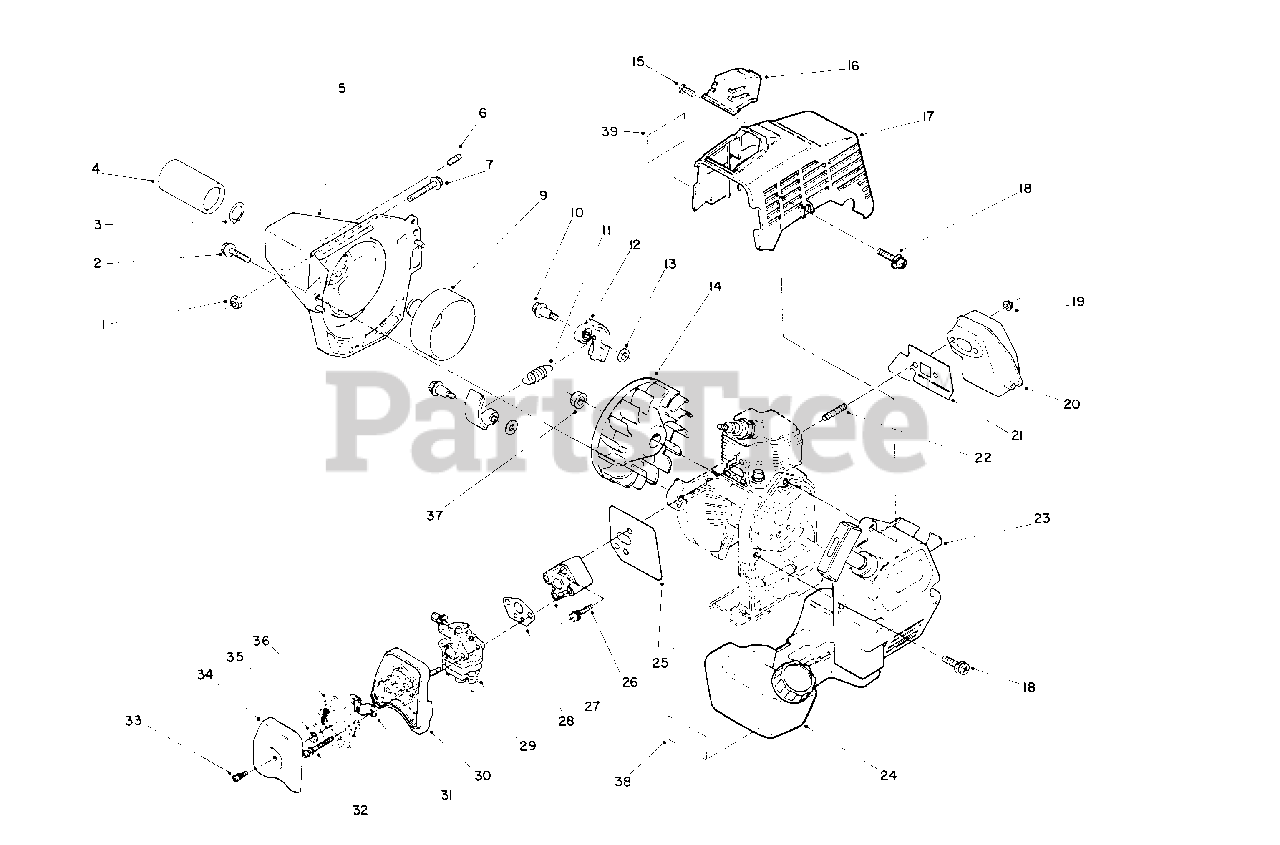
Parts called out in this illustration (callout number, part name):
1	Nut-Lock
2	Bolt/Washer
3	Ring-Retaining
5	Housing-Clutch
6	Screw-Set
7	Screw/Washer
9	Clutch-Drum
10	Bolt Clutch
11	Spring
12	Flyweight
14	Fan
16	Guard-Spark Plug
17	Cover-Top
18	Screw/Washer
19	Nut-Flanged
21	Gasket-Muffler
23	Starter-Recoil
24	Fuel Tank Assembly
25	Gasket-Insularor
26	Screw/Washer
27	Insulator
28	Gasket-Carburator
29	Carburator Assembly
30	Case-Air Cleaner
32	Screw/Washer
33	Screw/Washer
34	Cover-Air Cleaner
36	Element-Air Cleaner
37	Nut-Conical
38	Decal-Fuel
39	Decal-Hot
